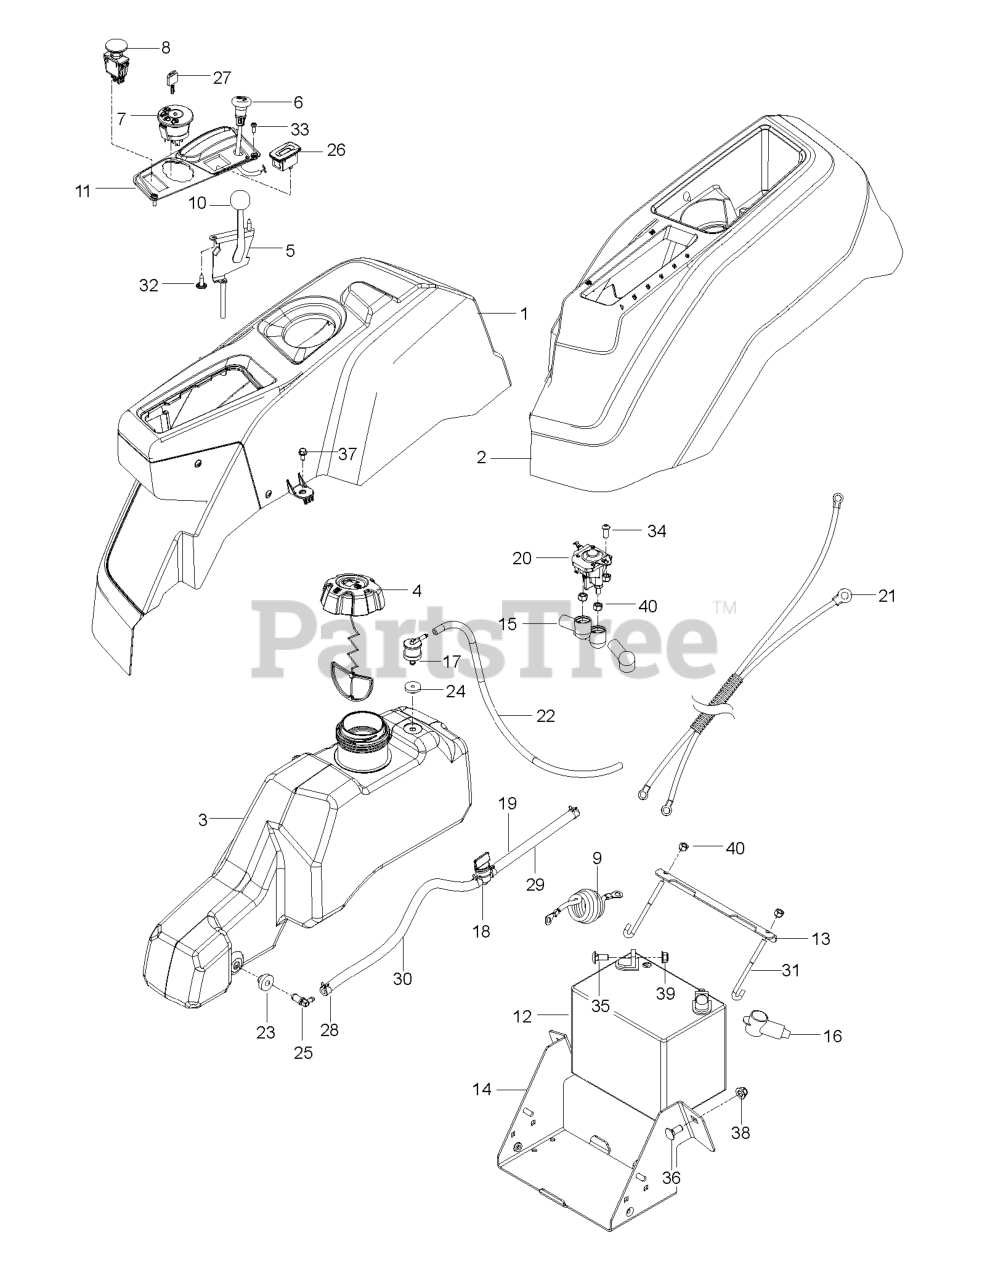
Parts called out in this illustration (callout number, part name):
1	CONSOLE.ASSY.RZ.REFRESH.RH
2	CONSOLE.LH.ASM
3	TANK.ASM3"NECK.NOCAP.NOSHDRZ18
4	CAP ASSY FUEL 3" GRAY
5	THROTTLE CONTROL W/BALL KNOB
6	CHOKE.PUSH-IN.STYLE.57"
7	RP IGNITION SWITCH
8	RP SWITCH.PTO.TERMINAL.STD.RED
9	CABLE BATTERY POS RZ
10	KNOB.ROUND.BALL.BLACK
11	CONTROL.PANEL.RZ.REFRESH.RH
12	BATTERY WET NOT SELLABLE
13	BRACKET.PNT.MOUNT.BATTERY.EDIP
14	BOX.PNT.BATTERY.RZ.EDIP
15	TERMINAL COVER
17	VALVE.FUEL.CHECK
18	FUEL VALVE
19	FUEL.HOSE.SHUT.OFF.ASM.10".3"
20	SOLENOID.STARTER.BRASS.PLUNGER
21	HARNESS.BTTRY.CABLE.RZ.REFRESH
22	HOSE 3/16" VAPOR LINE 29" LENG
23	BUSHING OUTLET T
24	GROMMET.ROV.SENTEC
25	STEM FUEL TANK
26	GUAGE.SRVCMNDR.HRMTR.
27	KEY.CHAIN.BLISTER.PACK.GEN.USA
28	HOSE CLAMP
29	HOSE.1/4".LOW.PERM.FUEL.LN.10"
30	HOSE.1/4".LOW.PERM.FUEL.LN.3"
31	HOOK.J.BATTERY
32	SCREW.PAN.HEAD.#10
33	SCREW 6-19X.437
34	SCR 1/4-20 X 5/8 BTN SKT HD ZD
35	BOLT 5/16C X 3/4" CARRIAGE
36	RHSNB 3/8C X 1
37	SCREW
38	NUT 3/8-16 HEX FLG NYLOC ZD
39	5/16-18 NYLOC FLANGE NUT
40	NUT.1/4-20.HEX.NYLOC.ZD
